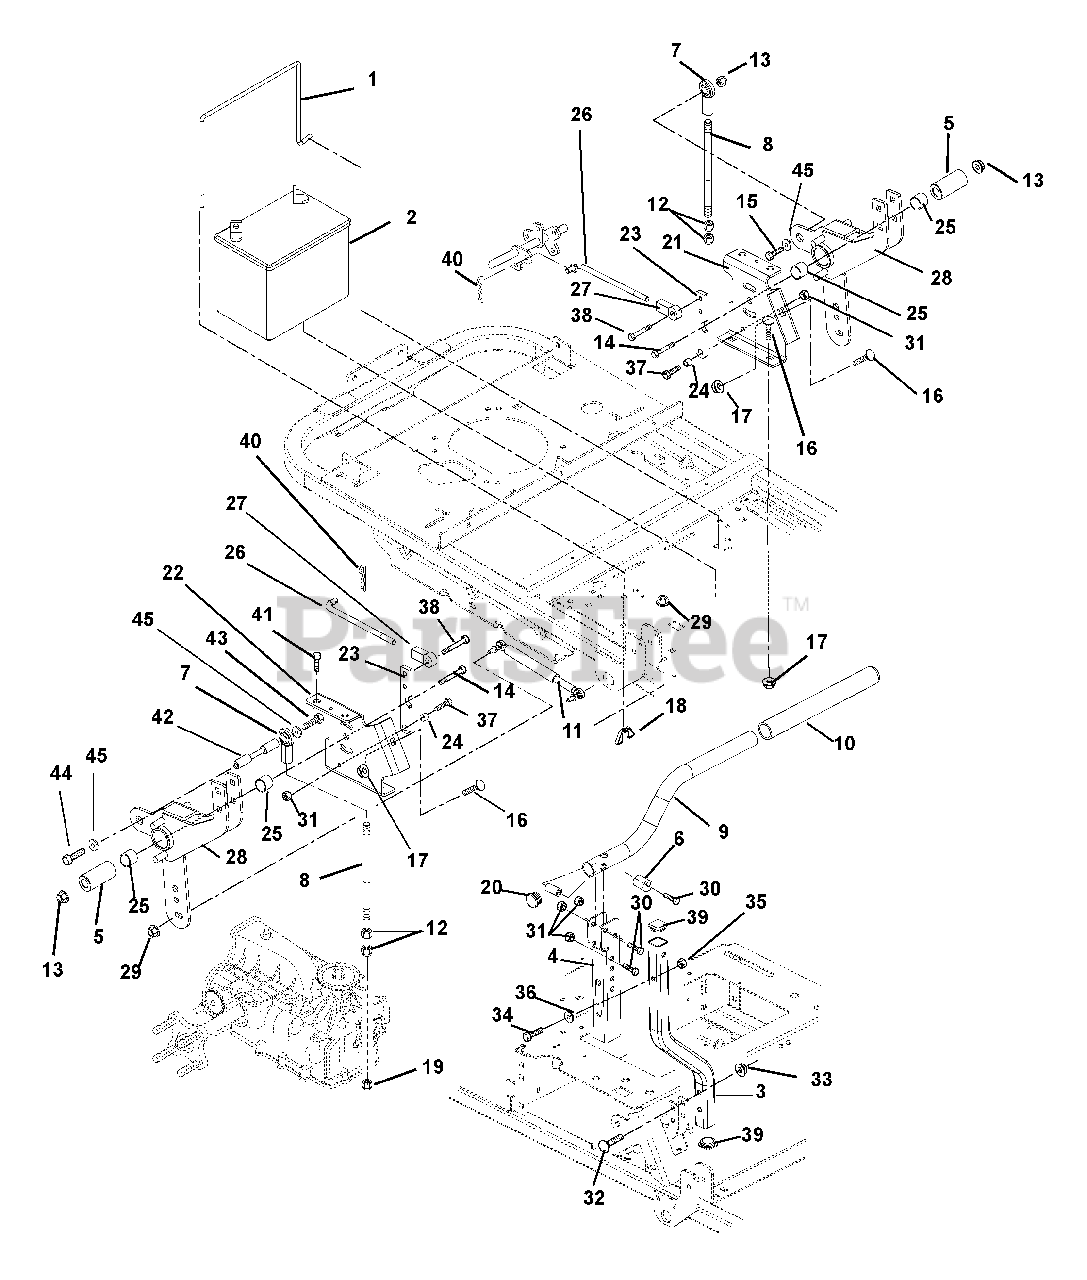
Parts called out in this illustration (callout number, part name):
1	BATTERY ROD
2	BATTERY, 300 CCA 10U1L
3	CONTROL ARM
4	CHANNEL, HANDLEBAR ADJUSTMENT
5	BSHG, SPCR .502X.997X2.03 PM
6	BSHG,ECCEN .328X.750X1.01 PM
7	ROD END, 1/2 RH
8	ROD-TRANSAXLE LH
9	HANDLEBAR
10	GRIP - HANDLEBAR
12	NUT-JAM .50-20 GR2 YWZC
13	@NUT-LK-TOP-FLG .50-13 YWZC
14	@BLT-HEX .50-13X3.00 GR5 YWZC
15	@BLT-HEX .50-13X1.75 GR5 YWZC
16	@BLT-RDHDSQNK .38-16X1.00 G5YZ
17	@NUT-LK-NYL-FLG .38-16 YWZC
18	NUT-LK WING .250-20 YWZC
19	NUT-LK-JAM-NYL .50-20 GR2 YWZC
20	CAPLUG, HANDLEBAR
21	WMT, CONTROL LH
22	WMT, CONTROL RH
23	BRACKET, NEUTRAL STOP
24	BSHG, SPCR .330X.500X.385
25	BRG, 1.00 X 1.12 X .75
26	LINK, BRAKE ROD
27	ROD END, .38 RH
28	WMT, STEERING CONTROL
29	NUT, TOP LOCK FLG 8X1.25 YWZC
30	@BLT-HEX .31-18X1.75 GR5 YWZC
31	@NUT-LK-NYL-FLG .31-18 YWZC
32	@BLT-RDHDSQNK .31-18X1.75 G5YZ
33	@NUT-LK-TOP-FLG .31-18 YWZC
34	@BLT-HEX .25-20X1.75 GR5 YWZC
35	@NUT-LK-NYL .250-20 YWZC
36	BSHG-FLG .265X.437X.250X.750
37	@BLT-HEX .31-18X1.25 GR5 YWZC
38	@BLT-HEX .38-16X.75 GR5 YWZC
39	CAPLUG SQR 1-14-20
40	PIN-HAIR INT .08X.18X1.18 YWZC
41	SCR-CAP .38-16X2 HSHD PRECT 30
42	LINKAGE, STEERING
43	@BLT-HEX .50-13X1.25 GR5 YWZC
44	@BLT-HEX .50-13X1.00 GR5 YWZC
45	WSHR-LK .500X.151 HVY YWZC
